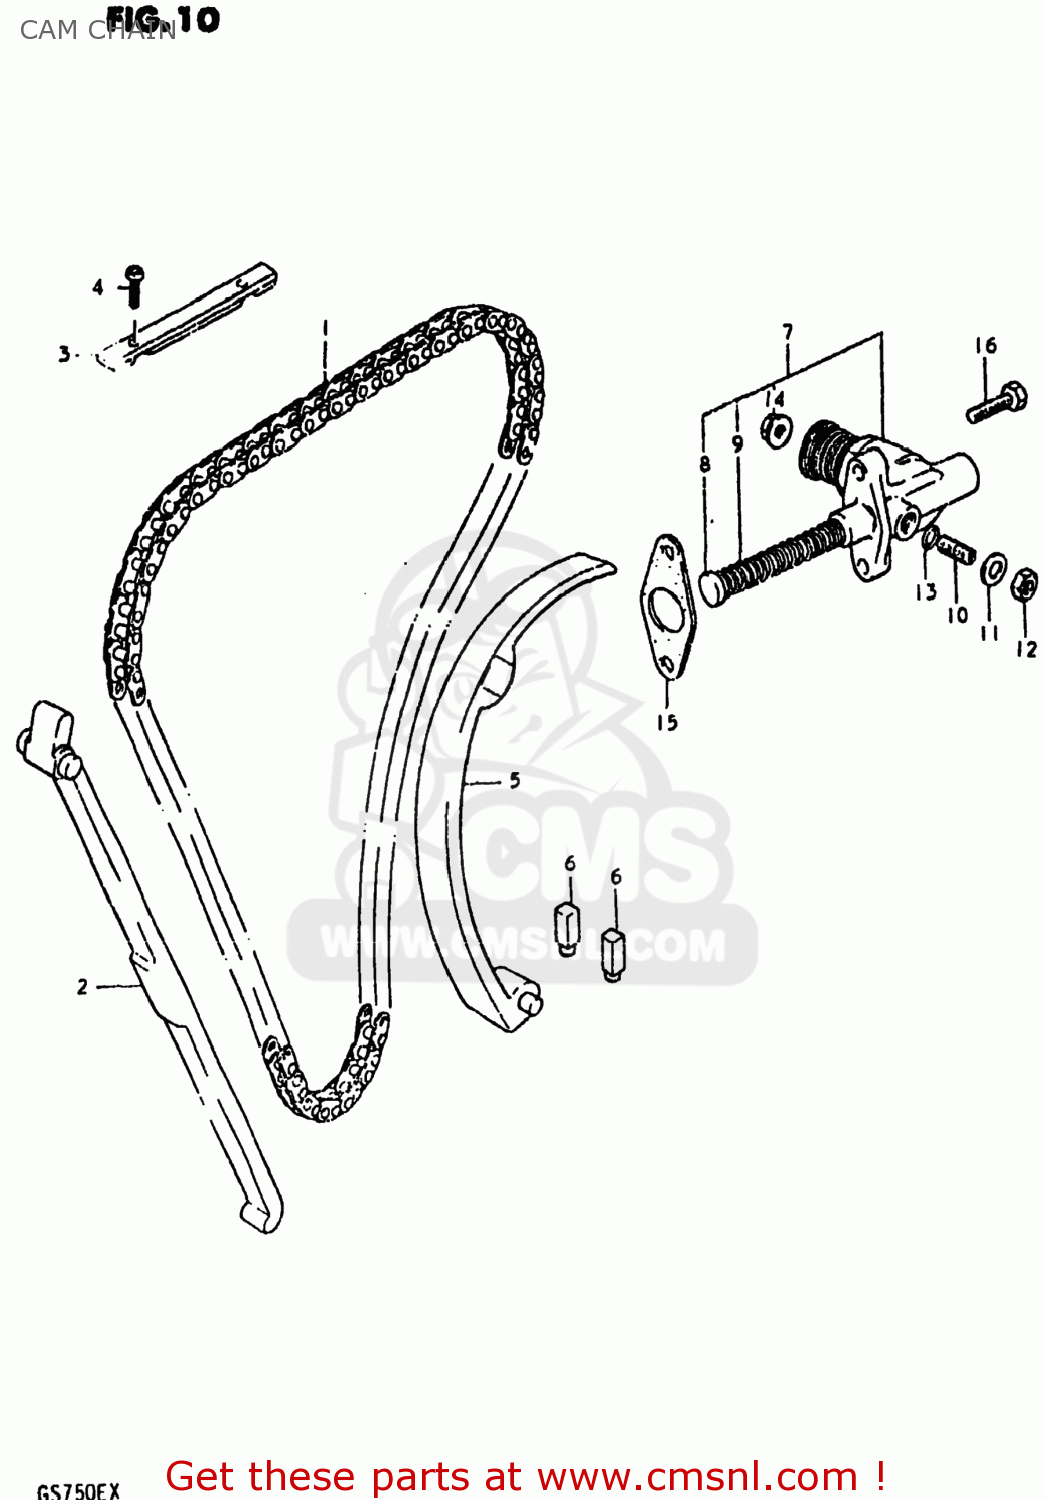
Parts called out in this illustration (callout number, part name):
1	CHAIN,CAMSHAFT DRIVE
2	GUIDE,CAM CHAIN NO.1
3	GUIDE,CAM CHAIN NO.3
4	SCREW
5	TENSIONER,CAM CHAIN
6	CUSHION,CAM CHAIN TENSIONER
7	ADJUSTER ASSEMBLY,TENSIONER
8	ROD,PUSH
9	SPRING
10	SCREW
11	WASHER
12	NUT
13	O-RING
14	NUT
15	GASKET,TENSIONER ADJUSTER (MCA)
16	SCREW (6X25)
